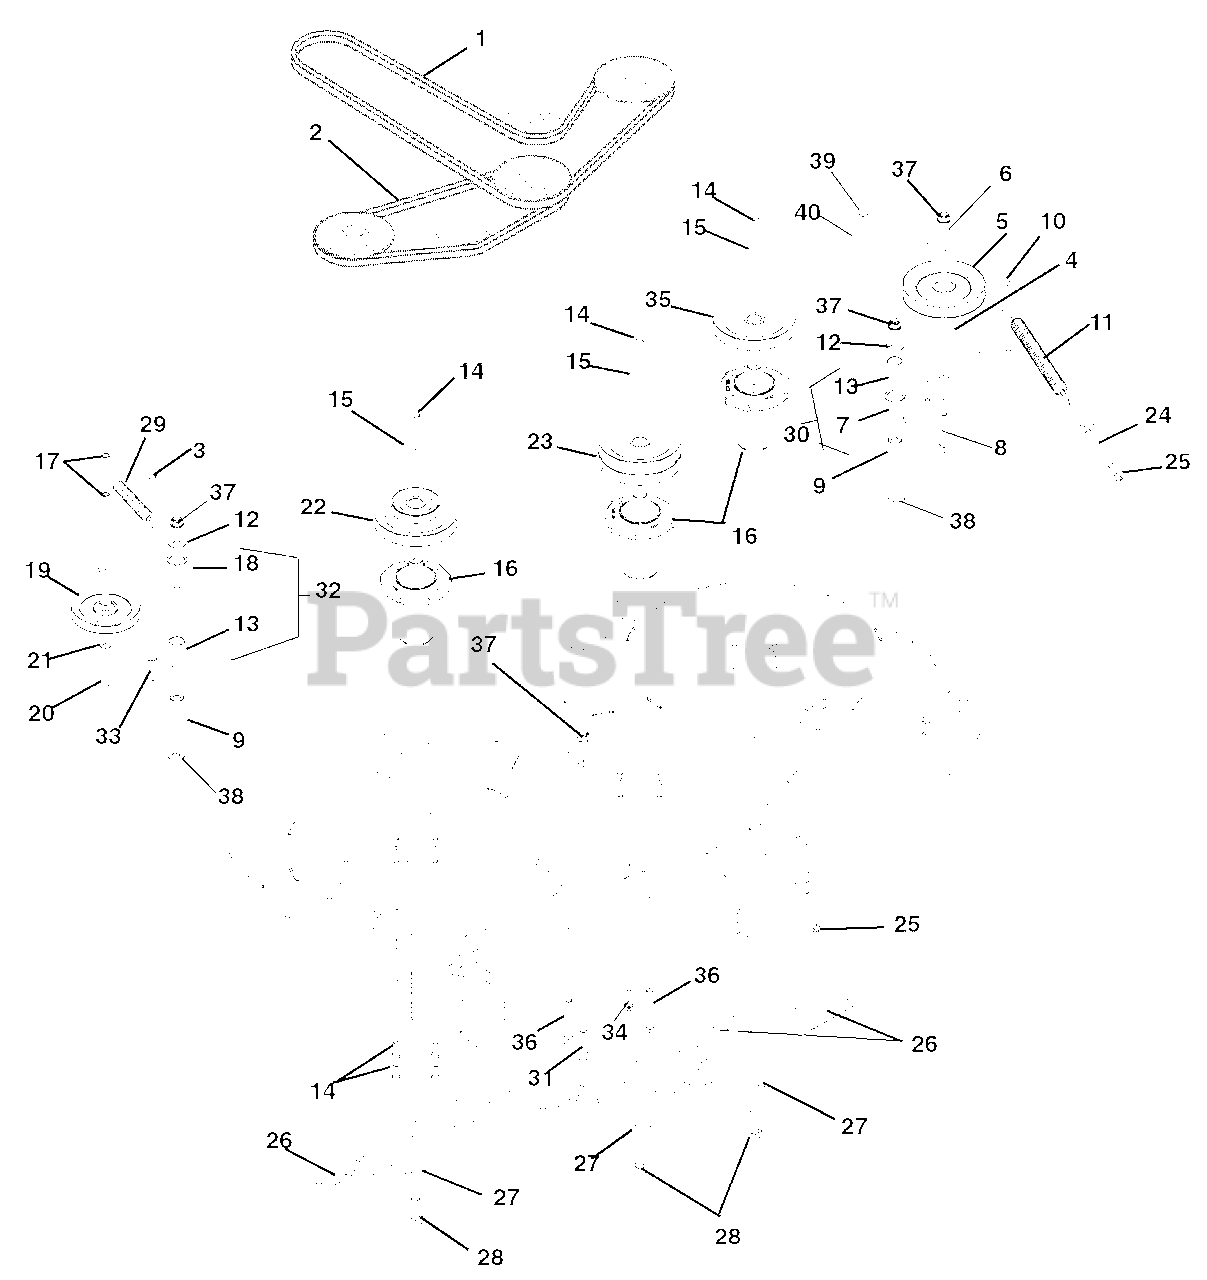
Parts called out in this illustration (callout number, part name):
1	HEX BELT, BB-WRAPPED
2	V-BELT, B-COGGED
3	@BLT-HEX .38-16X1.50 GR5 YWZC
4	BSHG, SPCR .502X.997X.50 PM
5	SHV, .50"ID X 6.00"OD V-IDLER
6	CAP, IDLER BEARING SEALING
7	WMT, IDLER ARM
8	@BLT-RDHDSQNK .50-13X3.00 G5YZ
9	BSHG, SPCR .502X.997X2.03 PM
10	BLT,SHLDR EP .38-16X.30 HEX YZ
11	SPRING, EXTENSION
12	@WSHR-FL-STL.563X1.38X.109YWZC
13	BSHG, 1.00 X 1.125 X 1.937
14	BLT-HEX .38-16X1.0 GR8 YZ EP30
15	WSHR,FLT STL.406X1.50X.245YWZC
16	ASM,MAINT FREE SPINDLE
17	@NUT-LK-CTR .38-16 YWZC
18	WMT, IDLER ARM
19	SHV, .38"ID X 5.00"OD V-IDLER
20	@BLT-HEX .38-16X2.25 GR5 YWZC
21	@WSHR-FL-STL.406X.812X.065 YWZ
22	PULLEY, DBL-1"IDX6.75"&4.25"OD
22	PULLEY, DOUBLE-1"IDX3.50"&6.0
23	PULLEY, DOUBLE-1"ID X 6.75"OD
23	PULLEY, DOUBLE
24	BOLT, .38-16X4.50 .62 DIA EYE
25	NUT-HEX-JAM .375-16 YWZC
26	BLADE, 20.5"
26	BLADE, 18"
27	WSHR-BLVL .669X1.535X.138
28	BLT-HEX .62-18X1.75 GR8 YWZC
29	SPRING, EXTENSION
30	ASM, IDLER PIVOT ARM (PTO)
31	BLT-RDHDSHSQNKFT.50-13X1.50 G5
32	ASM, IDLER ARM (DECK)
33	NUT COUPLING .375-16X1.75
34	@BLT-RDHDSHSQNK.38-16X1.0 G5YZ
35	PULLEY, V-1" ID X 6.75" OD
35	PULLEY, SINGLE-1"ID X 6" OD
36	@BLT-RDHDSQNK .50-13X3.50 G5YZ
37	@NUT-LK-NYL-FLG .50-13 YWZC
38	WSHR-FLT .640X1.75X.250
39	@BLT-HEX .38-16X2.75 GR5 YWZC
40	@NUT-HEX .38-16 YWZC
